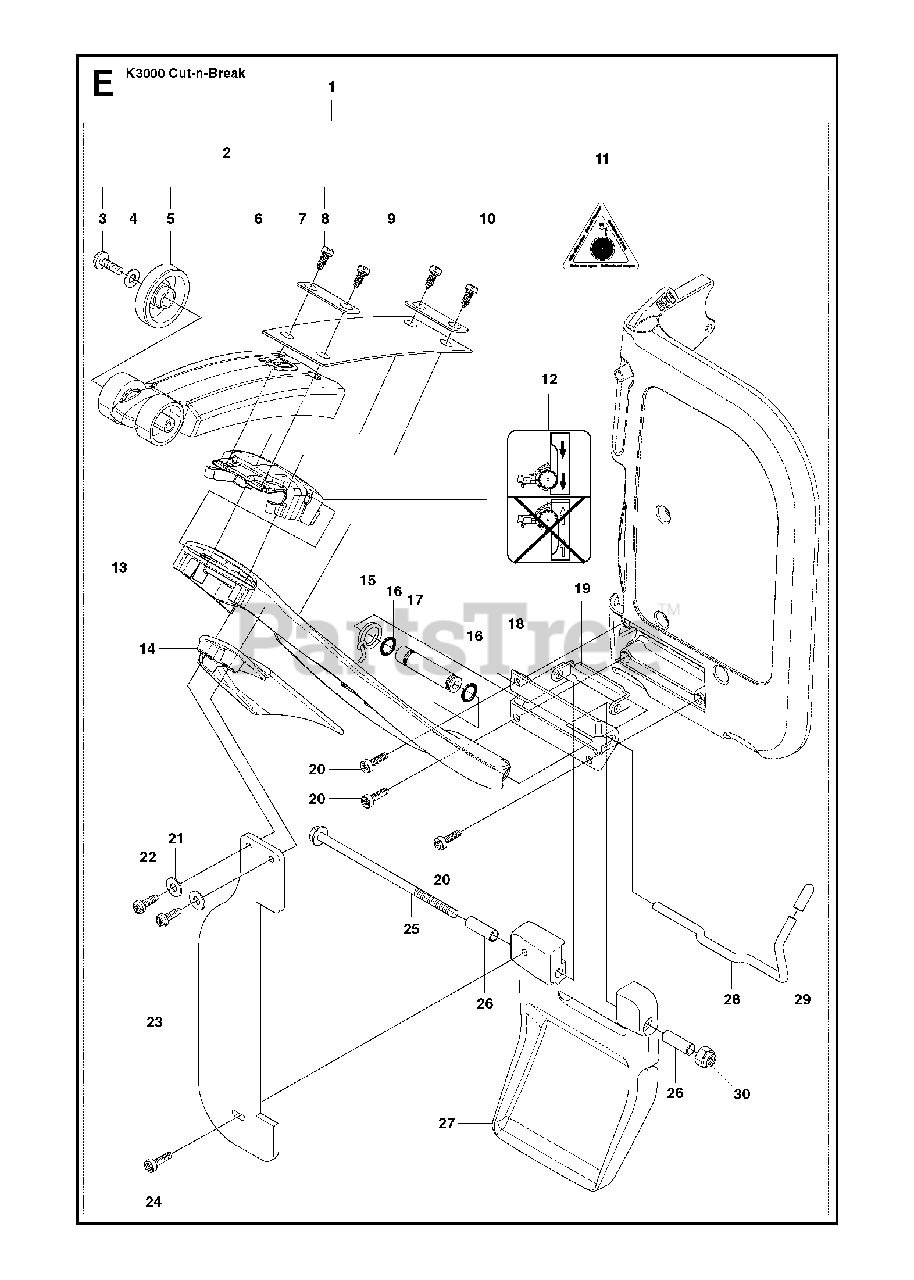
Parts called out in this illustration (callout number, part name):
1	SPRAY GUARDIncl. 2, 11 - 28
2	SPRAY GUARDIncl. 3 - 10
8	SCREW CRPANT
20	SCREW ITXSCT
22	SCREW CCRPANT
